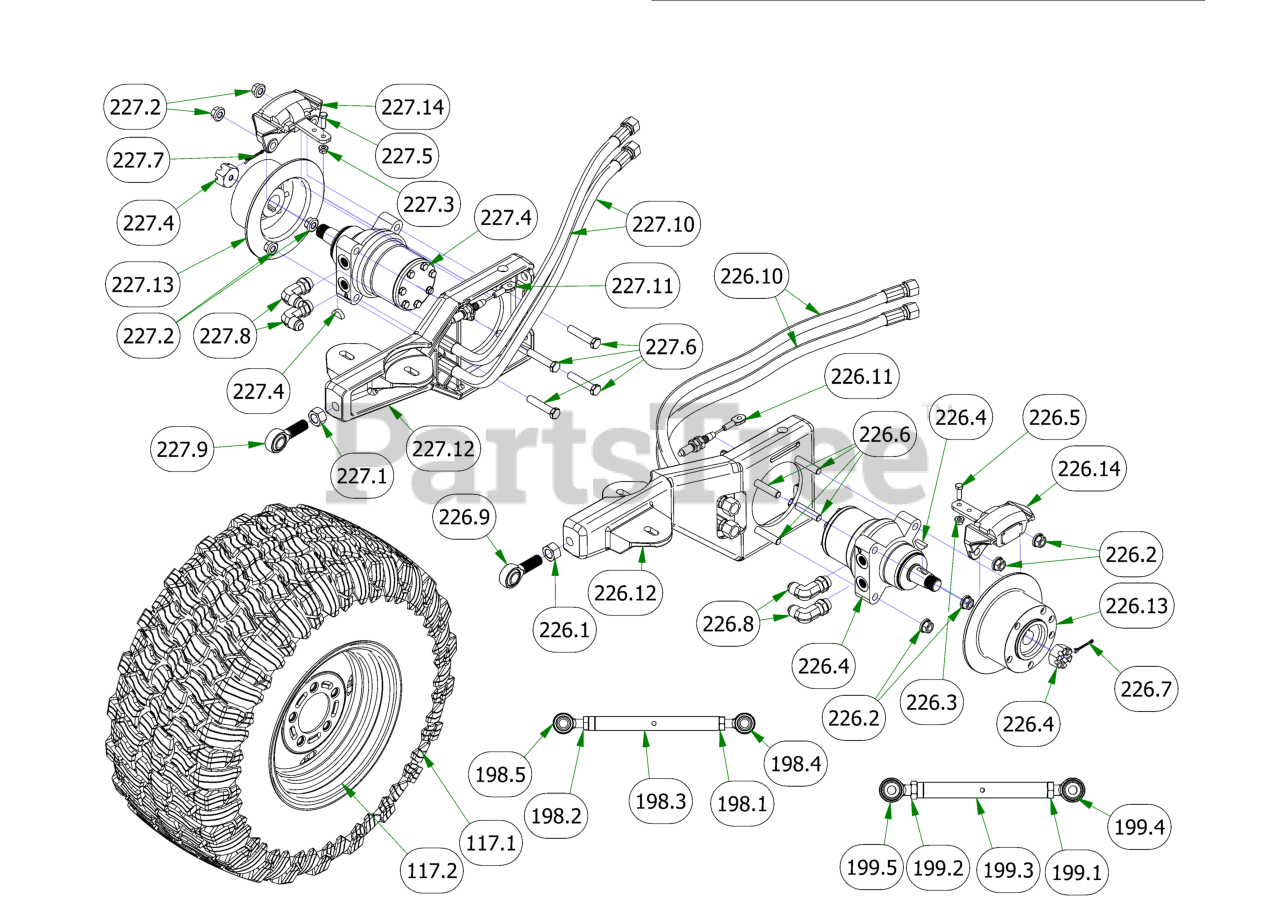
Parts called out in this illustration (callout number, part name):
117	2019 Assy-26x12-12 Reaper Turf -10.5" Rim
117.1	2019 26x12-12 Reaper Turf Tire
117.2	2019 10.5" Wheel
198	2019 Suspension Radius Rod Assembly
198.1	5/8-11 HEX JAM NUT ZINC
198.2	NUT, 5/8-18LH
198.3	2019 Suspension Link Body
198.4	2019 RH 5/8" Heim
198.5	2019 LH 5/8" Heim
199	2019 Suspension Radius Rod Assembly
199.1	3/4-16 HEX JAM NUT ZINC
199.2	3/4-16 LH HEX JAM NUT ZINC
199.3	Rear Radius Rod, 3/4 Body
199.4	3/4-16 x 5/8 RH Heim
199.5	3/4-16 x 5/8 LH Heim
226	2019 Renegade Trailing LH Arm Assy
226.1	3/4"-16 Fine Full Nut
226.2	1/2-13 Gr 8 Centerlock Flange Nut
226.3	5/16-18 NYLON INSERT FLANGE LOCKNUT ZINC
226.4	18cc Parker Wheel Motor- Left
226.5	5/16-18 X 1 HEX CAP SCREW (GR.5) ZINC
226.6	1/2-13 x 2.75 Gr. 8 Hex Head Bolt
226.7	1/8 X 1-1/2 COTTER PIN ZINC
226.8	2019 Rouge/Renegade Wheel Motor 90* Fitting #6801-10L
226.9	3/4-16 RH Male Rod End
226.10	2019 Renegade Hydro Hose
226.11	2019 Short Brake Cable-Suspension Models
226.12	2019 Left Trailing Arm
226.13	Brake Disk
226.14	XP/AOS Left Brake Caliper
227	2019 Renegade Trailing RH Arm Assy
227.1	3/4"-16 Fine Full Nut
227.2	1/2-13 Gr 8 Centerlock Flange Nut
227.3	5/16-18 NYLON INSERT FLANGE LOCKNUT ZINC
227.4	18cc Parker Wheel Motor- Right
227.5	5/16-18 X 1 HEX CAP SCREW (GR.5) ZINC
227.6	1/2-13 x 2.75 Gr. 8 Hex Head Bolt
227.7	1/8 X 1-1/2 COTTER PIN ZINC
227.8	2019 Rouge/Renegade Wheel Motor 90* Fitting #6801-10L
227.9	3/4-16 RH Male Rod End
227.10	2019 Renegade Hydro Hose
227.11	2019 Long Brake Cable-Renegade, Rogue
227.12	2019 Right Trailing Arm
227.13	Brake Disk
227.14	XP/AOS Right Brake Caliper
